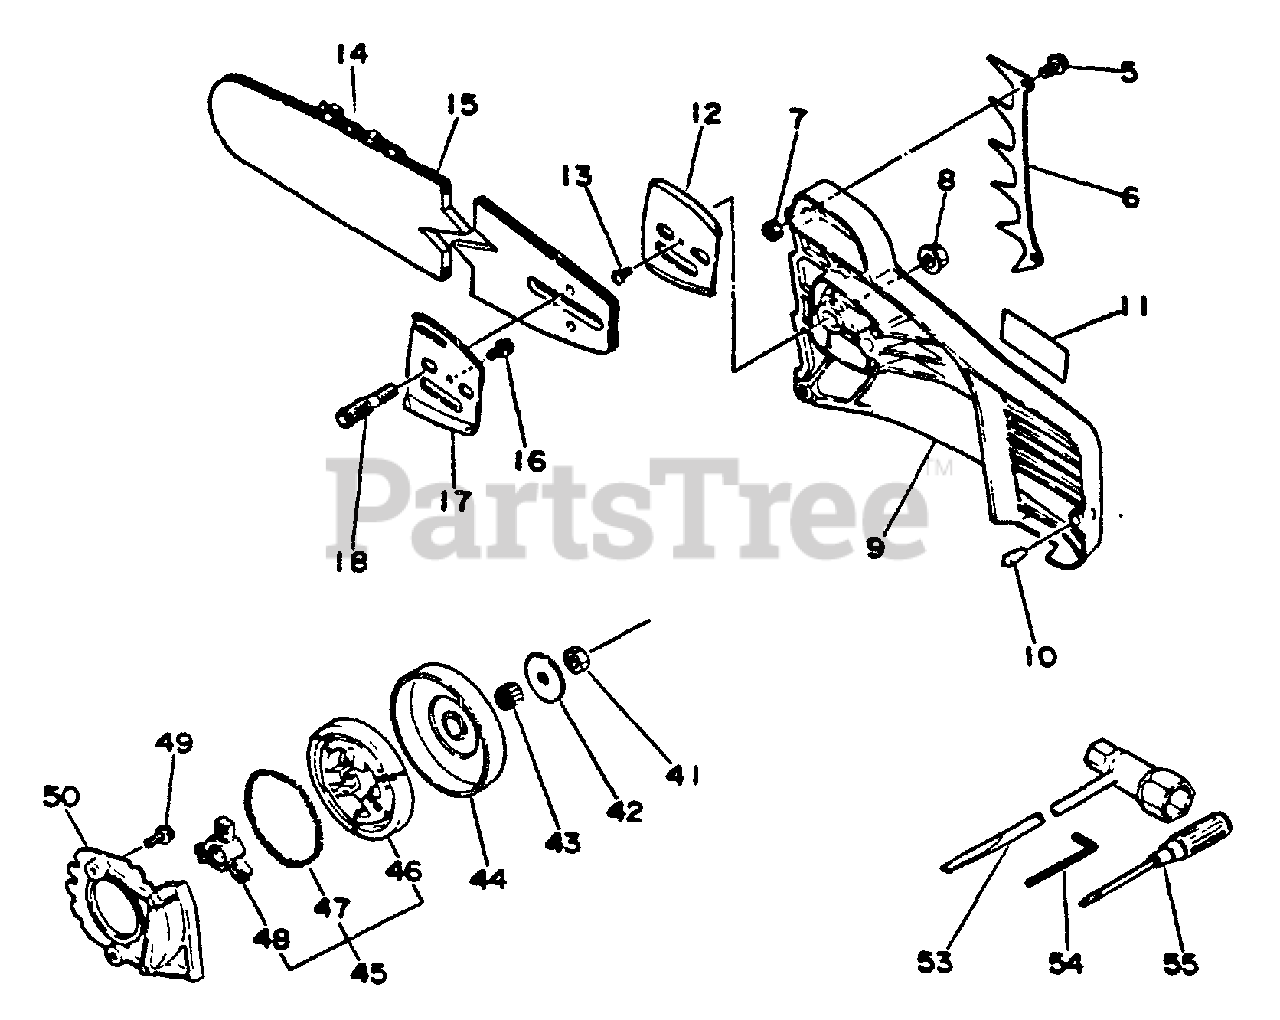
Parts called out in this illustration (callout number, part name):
5	SCREW - 5X12
6	SPIKE
7	LOCKNUT - 5
8	NUT - FLANGE
9	GUARD, SPROCKET
10	PIN - LOCATING
11	LABEL - ECHO
12	PLATE, GUIDE - OUTER
13	SCREW - 3X6
14	Chain
15	GUIDE BAR
16	SCREW - 4X10
17	PLATE, GUIDE - INNER
18	STUD, GUIDE BAR
41	LOCKNUT
42	WASHER, CLUTCH
43	BEARING, NEEDLE
44	DRUM, CLUTCH
45	CLUTCH ASSY
46	SHOE, CLUTCH
47	SPRING, CLUTCH
48	HUB, CLUTCH
49	SCREW - 4X14
50	SEAL, DUST
53	T-WRENCH - 13X19mm
54	HEX KEY - 4mm
55	SCREWDRIVER
